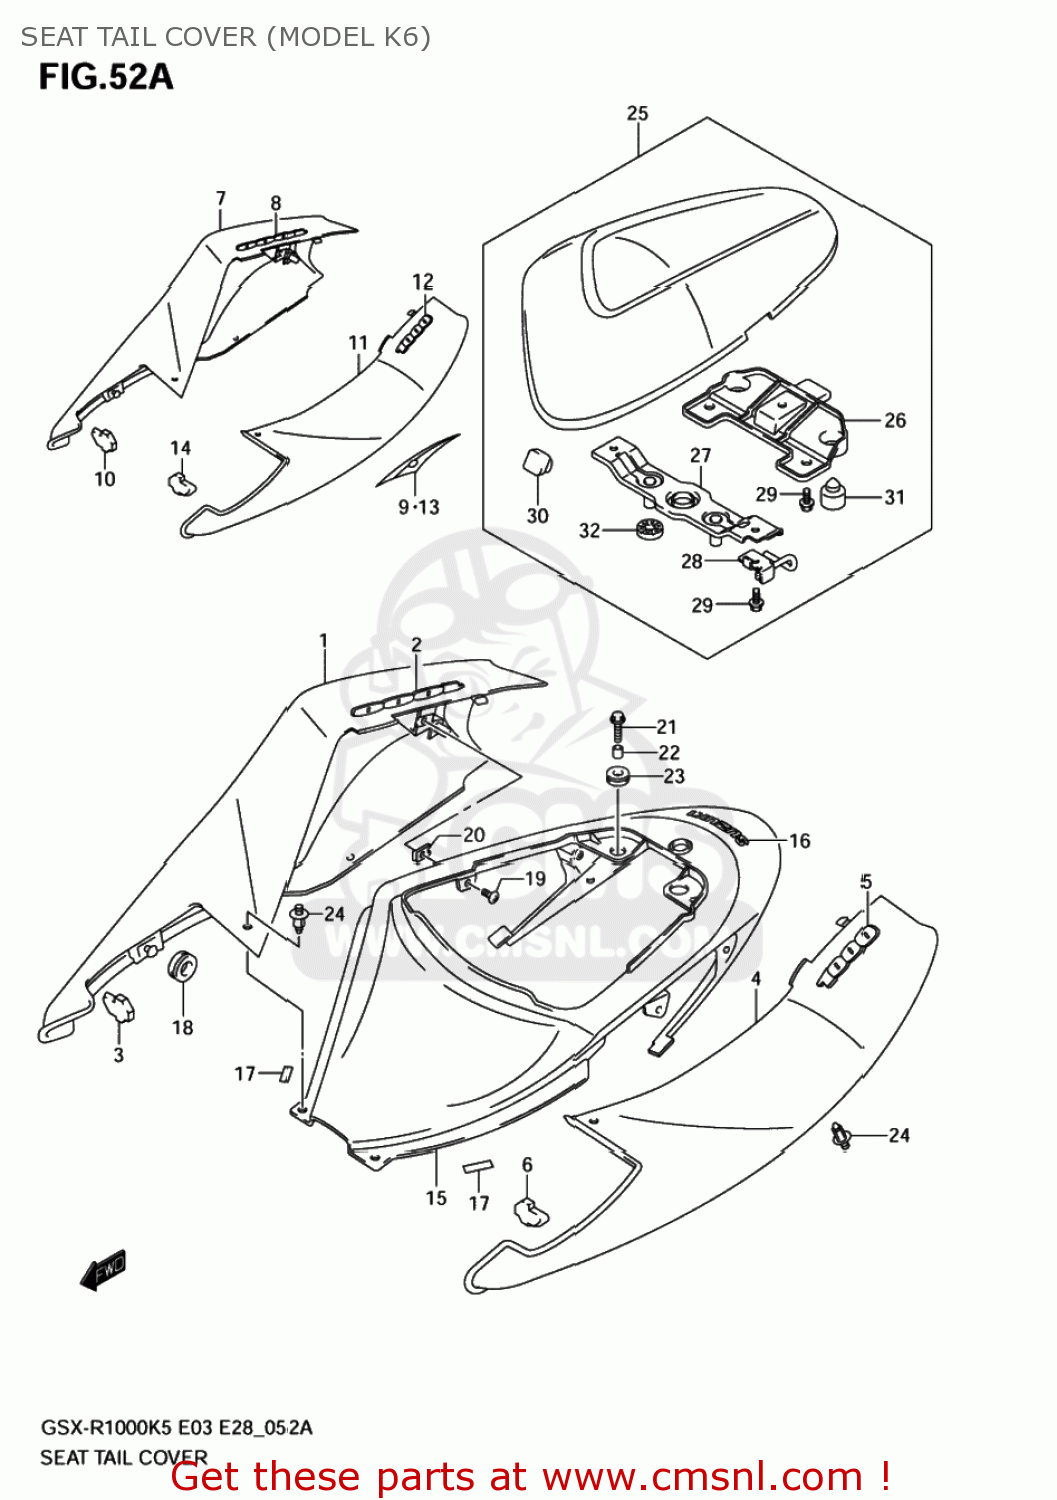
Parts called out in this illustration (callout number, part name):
1	COVER,SEAT TAI
2	EMBLEM,1000
3	CUSHION,SEAT TAIL COVER,R
4	COVER,SEAT TAI
5	EMBLEM,1000
6	CUSHION,SEAT TAIL COVER,L
7	COVER,SEAT TAI
8	EMBLEM,1000
9	TAPE,SEAT TAIL COVER,R
10	CUSHION,SEAT TAIL COVER,R
11	COVER,SEAT TAI
12	EMBLEM,1000
13	TAPE,SEAT TAIL COVER,L
14	CUSHION,SEAT TAIL COVER,L
15	COVER,SEAT TAIL CTR
16	EMBLEM,SUZUKI
17	TAPE(6X25X0.13)
18	CUSHION
19	SCREW
20	NUT
21	BOLT(6X20)
22	SPACER(6.5X10X9.4)
23	CUSHION
24	CLIP(BLACK)
25	BOX,SEAT TAIL
26	BOTTOM,SEAT TAIL BOX
27	STRIKER
28	HOLDER,HELMET
29	BOLT
30	CUSHION
31	CUSHION
32	CUSHION
